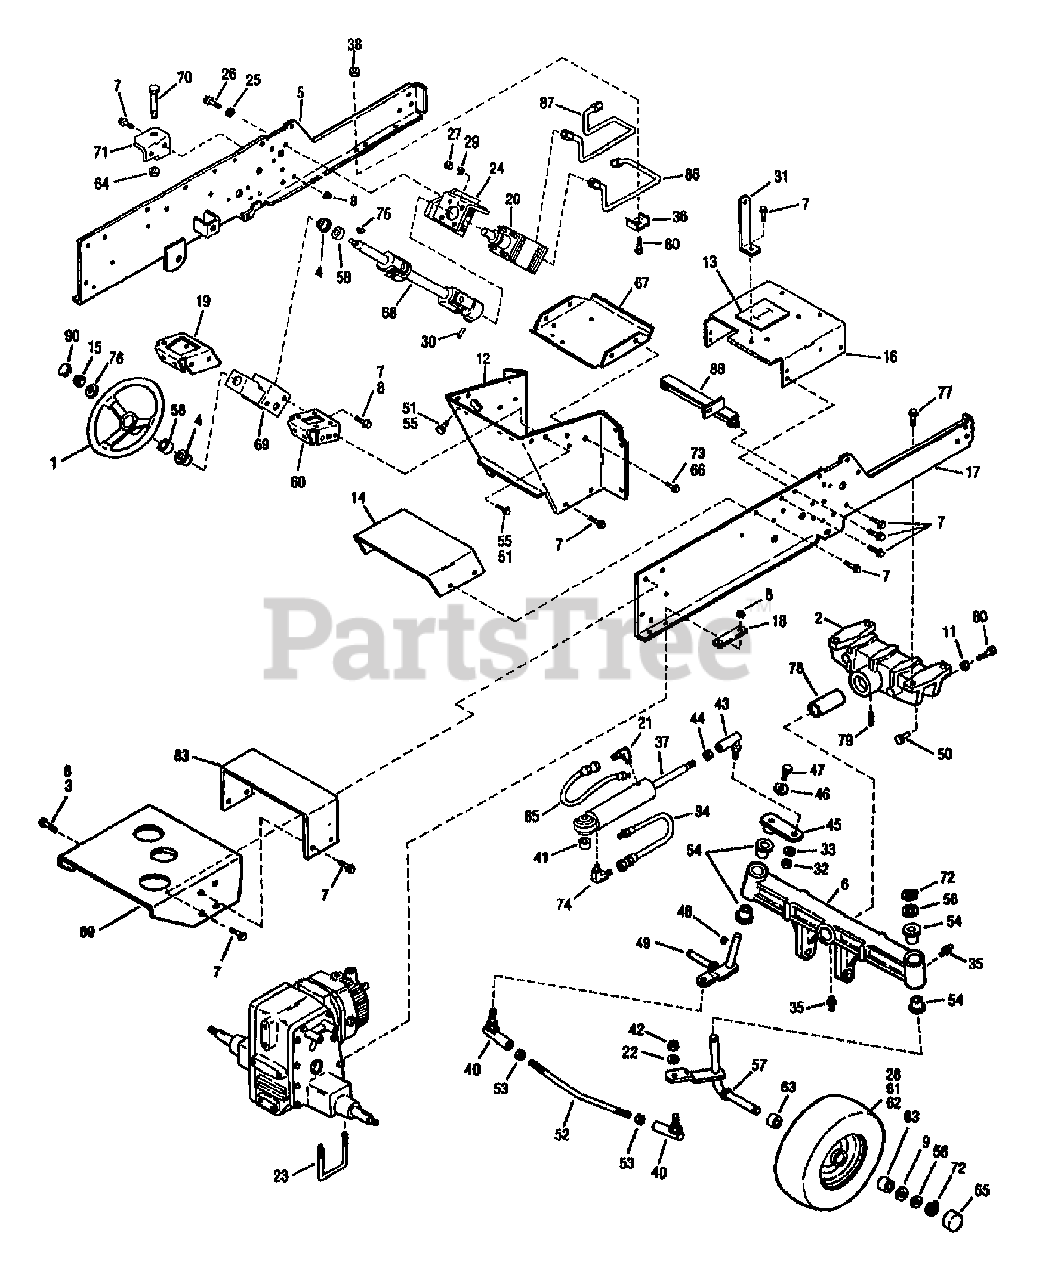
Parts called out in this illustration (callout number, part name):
1	WHEEL-STEERING
2	BOLSTER-FRONT AXLE
3	SCR-HFLK 3/8-16X1.00 ZP
4	BEARING-FLANGED NYLON
6	AXLE-FRONT
8	NUT-HFLK 3/8-16 ZP
9	SPACER-1.75X1.015X.179
11	NUT-HEX JAM 5/16-18
12	SUPPORT
14	TUNNEL W/DECAL
15	NUT-H/LK 3/8-16
16	SUPT-BATTERY/FUEL TANK
18	DOUBLER-FRAME REAR
19	STEERING BRACKET
20	KIT-STEERING VALVE
21	ELBOW
22	WASHER-LK .5
23	BOLT-U
24	SUPT-STEERING PUMP
25	WASHER-LK .438 ZP
26	SCR-HH 1/2-14X1.00
27	NUT-HEX 5/16-24
28	STEM-VALVE
29	WASHER-LK .312 ZP
30	PIN-ROLL 1/4 X 1-1/4
31	BRACE-STEERING
32	NUT-HEX 5/8-18
33	WASHER-LK 1.072X.634X.156
34	ASSM-HOSE
35	FITTING-GREASE 1/4-28X2.00
36	CLAMP
37	CYLINDER-HYDRAULIC
38	NUT-TOP/LK 5/16-18 ZP
40	JOINT-BALL
41	SLEEVE-CYLINDER
42	NUT-H/LK 1/2-20 ZP
43	JOINT-BALL
44	NUT-HEX/JAM 5/8-18 ZP
45	ARM-STEERING
46	WASHER-1.75X.328X.1345
47	SCR-HFLK 5/16-18X.75 ZP
48	KEY-WOODRUFF .25X.875
49	SPINDLE-WHEEL LEFT
50	PIN-WELD
51	SCR-TRUSS HD 5/16-18X.62
52	ROD-TIE
53	NUT-JAM
54	BEARING-FLANGE
55	NUT-HFLK 5/16-18 ZP
56	WASHER-THRUST
57	SPINDLE-WHEEL RH
58	COLLAR
60	BRKT-STEERING
61	WHEEL
62	TIRE-16X6.50-8
63	BEARING-BALL
64	NUT-LOCK
66	SCR-HFLK 1/4-20X.50 ZP
67	CARRIER-BATTERY
68	ASSM-STEERING SHAFT
69	ASSM-SUPPORT
70	SCR-HH 5/8-11X3.0 G5
71	BRKT-CYLINDER
72	RING-HEAVY EXT HD 1.0 ID
73	NUT-HF/LK 1/4-20 ZP
74	ELBOW
75	KEY-WOODRUFF .188X.75
77	SCR-HFLK 3/8-16X1.00 ZP
78	TUBE-PIVOT AXLE
79	PIN-.312X.75
80	SCR-HH 5/16-18X1.0 G5 ZP
83	SUPPORT-FENDER
85	ASSM-HOSE
86	ASSM-TUBE
87	ASSM-TUBE
88	SUPPORT-FRAME
